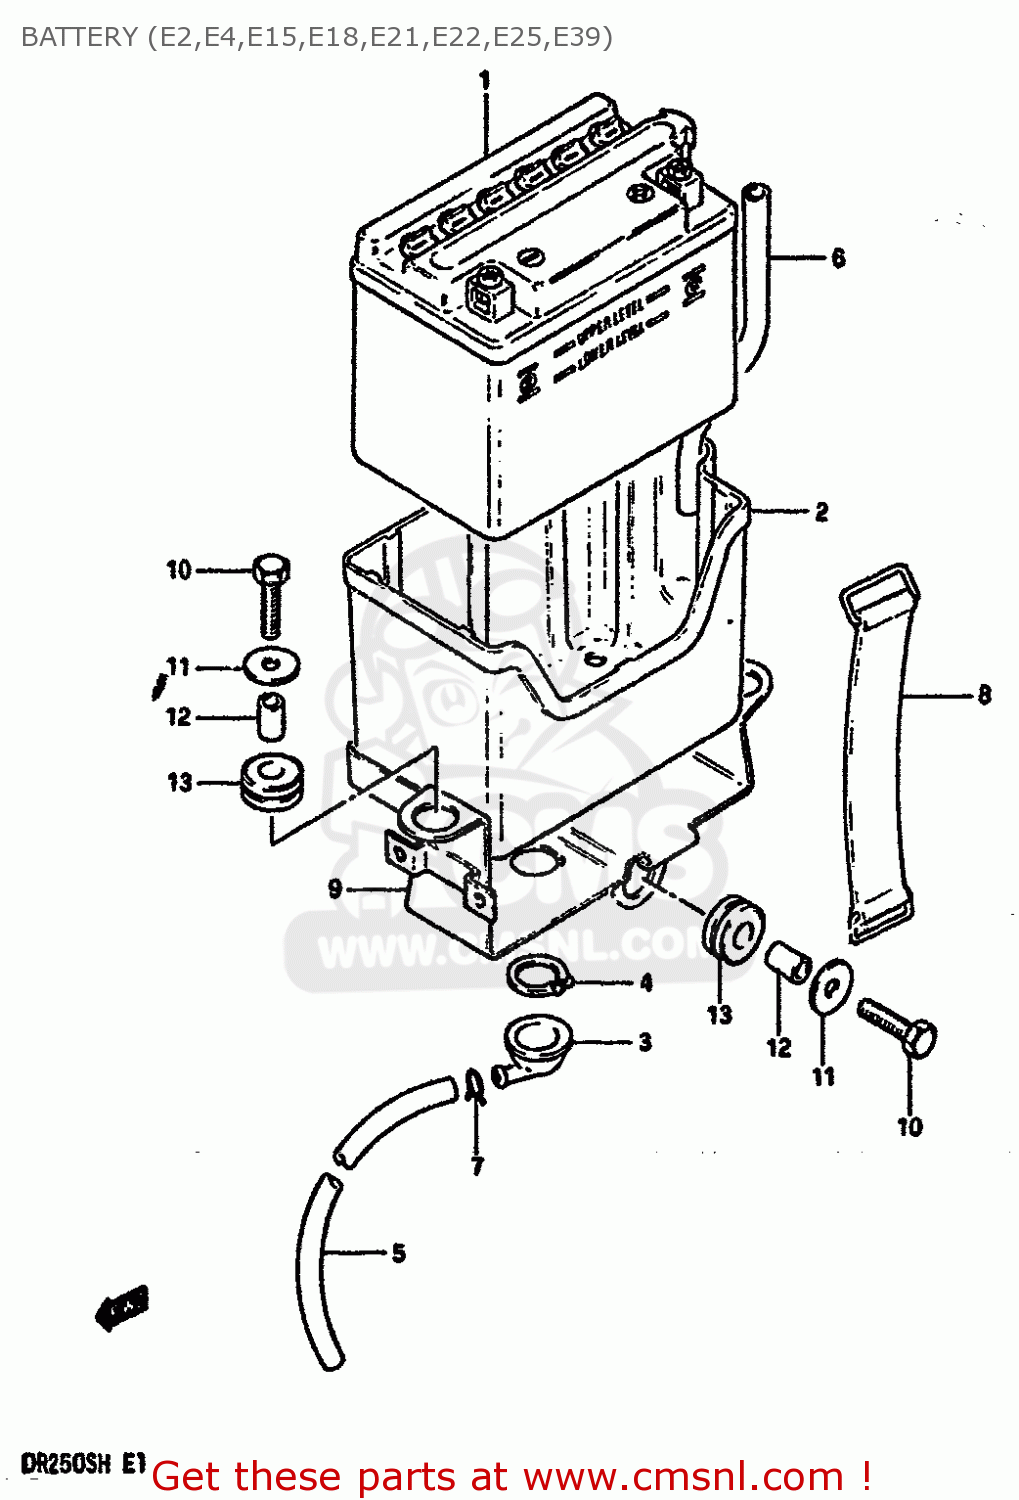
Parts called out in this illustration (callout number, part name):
1	BATTERY ASSY(YB4L-B,12V4.2AH)
2	CASE, BATTERY
3	FUNNEL,BATTERY EXHAUST
4	CIRCLIP
5	HOSE,BATTERY EXHAUST
6	HOSE,BATTERY EXHAUST
7	CLIP
8	BAND
9	HOLDER, BATTERY
10	BOLT
11	WASHER (6.5X20X1.2)
12	SPACER(6.1X9X7.5)
13	CUSHION
